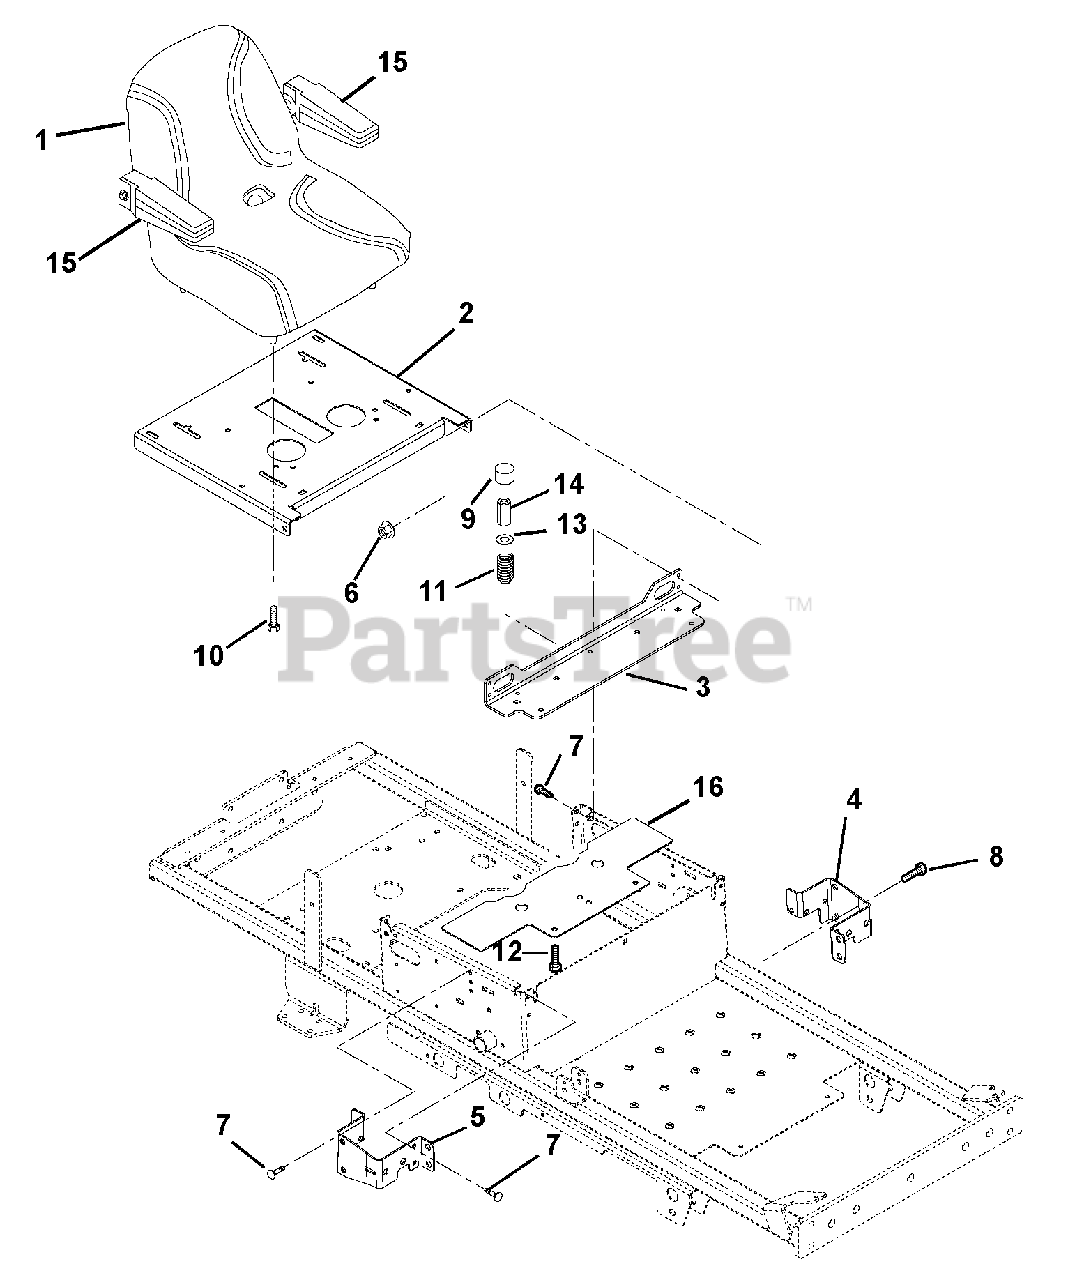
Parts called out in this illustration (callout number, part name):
1	Seat Assembly With Replaceable Arm Rests
2	Seat Plate
3	Bracket, Seat Spring
4	Stop, RH Steering
5	Stop, LH Steering
6	Nut, Locking Flange .38-16
7	Screw, Tapping .31-18 x .50
8	Bolt, Shoulder .375-16 x 1.50
10	Bolt, Hex .31-18 x .75 Grade 5
11	Spring, Seat
12	Bolt, Round Head Square Neck .31-18 x 1.50 Grade 5
13	Washer-Flat-Steel .328 x .87 x .179
14	Nut, Coupling 5/16-18 x 1
15	Replacement Arm Rest (1 per kit)
16	Guard, Finger
